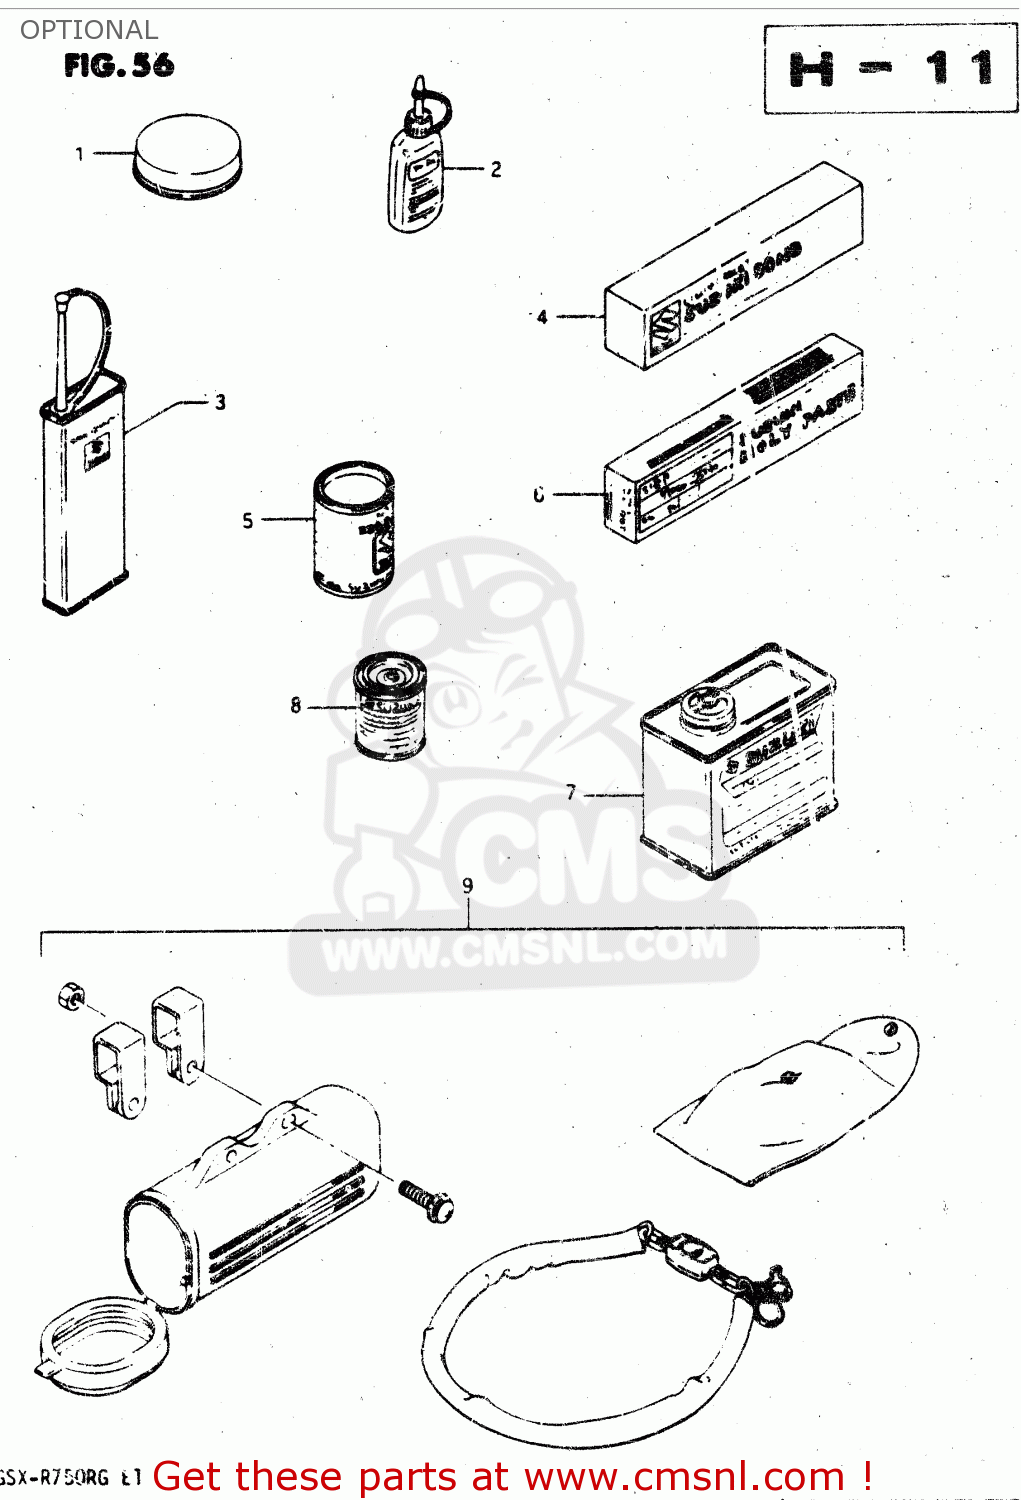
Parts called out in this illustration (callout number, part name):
1	GREASE,PBC FOR BRK PAD 20G
2	THREAD LOCK NO
3	THREAD LOCK NO.1401 CLEAR 200G
4	LIQUID GSKT NO.1207B 100G BLK
5	GREASE(C)EP2 LITHIUM 150G
6	SUZUKI MOLY PASTE
7	PAINT (SUPER WHITE)
8	PAINT BLIGHT S
9	LOCK SET,CHAIN
